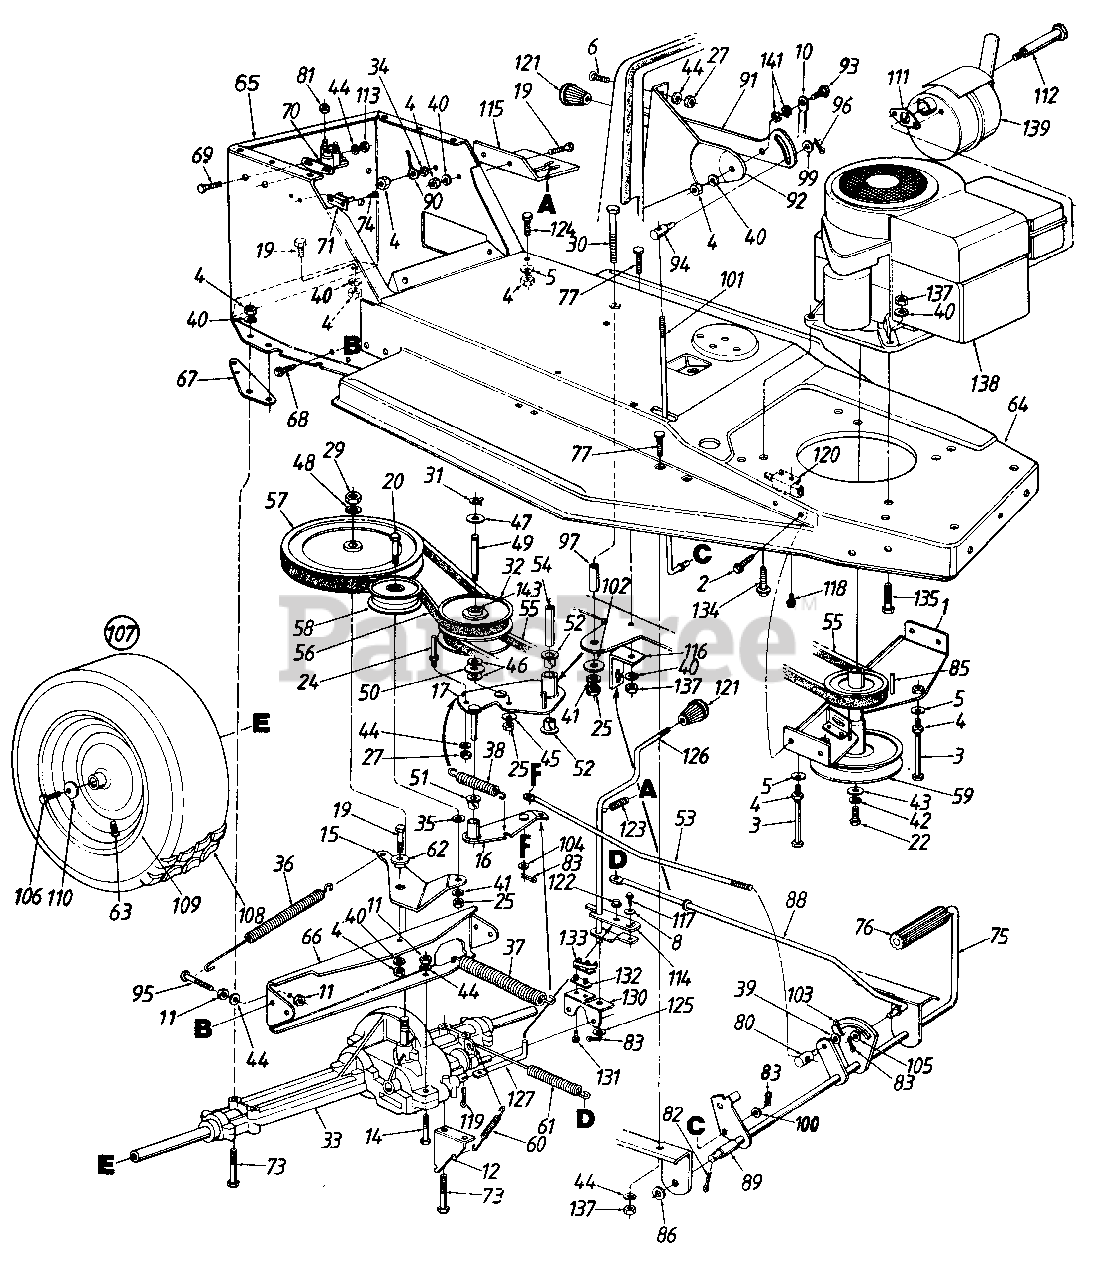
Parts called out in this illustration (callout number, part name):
1	Engine Pulley Belt Guard Ass'y.
2	Hex AB-Tap Scr. 1/4 x .62"
3	Hex Bolt 5/16-18 x 5-1/4" Lg.
4	Hex Nut 5/16-18 Thd.
5	Bell-Wash. .345" I.D. x .88
6	Truss-Mach. Scr. 1/4-20 x .50"
8	Bell-Wash. .265" I.D. x .75
10	Speed Selector Brace
11	Hex Nut 1/4-28 Thd.
12	Spring Retainer Brkt.
14	Hex Bolt 1/4-28 x 1.75" Lg.
17	Variable Speed Brkt. Ass'y.
19	Hex Bolt 5/16-18 x .75" Lg.
20	Hex Bolt 3/8-24 x 2.0" Lg. Grade 5
22	Hex Bolt 7/16-20 x 1.5" Lg.
24	Belt Guard Pin
25	Hex Nut 3/8-24 Thd.
27	Hex Nut 1/4-20 Thd.
29	Hex Jam Nut 1/2-20 Thd.
30	Hex Bolt 3/8-24 x 3.75" Lg.
31	Snap Ring
32	Variable Speed Pulley Ass'y.
33	Transaxle Complete
34	Ext. L-Wash. 5/16" I.D.
35	Fl-Wash. 3/8" I.D. x 1.0" O.D.
36	Extension Spring 6.12" Lg.
37	Extension Spring 7.5" Lg.
38	Extension Spring 2.59" Lg.
39	Fl-Wash. .385" I.D. x .620"
40	L-Wash. 5/16" I.D.*
41	L-Wash. 3/8" I.D.
42	L-Wash. 7/16" I.D.
43	Fl-Wash. .450" I.D. x 1.25"
44	L-Wash. 1/4" I.D.
45	Bell-Wash. .39" I.D. x 1.13"
46	Fl-Wash. .56" I.D. x 1.0" O.D.
47	Washer"Teflon" .565 I.D.
48	Bell-Wash. 1/2" I.D. x 1.0" O.D.
49	Shaft .56" Dia. x 3.875" Lg.
50	Thrust Brg. 1.25 O.D.
51	Flanged Nyliner Brg.
52	Nyliner Flanged Brg.
53	Speed Control Rod
54	Spacer
55	V-Belt
56	V-Belt
57	1/2 V-Pulley .501 " I.D. x 8.00"
58	Idler Pulley 3-1/8" Dia.
59	Dbl. Pulley 6.0" Dia. x 3.56"
60	Extension Spring 3.18" Lg.
61	Extension Spring 7.08" Lg.
62	Shld. Spacer .500" Dia.
63	Air Valve
64	Front Frame
65	Rear Frame
66	Transaxle Support Brkt.
69	Hex Bolt 1/4-20 x .62" Lg.
70	Solenoid
71	Circuit Breaker
73	Hex Bolt 5/16-18 x 2.75" Lg.
74	Truss Mach. B-Tap Scr. #10 x.50" Lg.
75	Foot Pedal Rod Ass'y.
76	Foot Pad
77	Ribbed Neck Bolt 5/16-24 x .84"
80	Ferrule
81	Hex Sems Nut 1/4-20 Thd.
82	Cot-Pin 1/8" Dia. x 1.25" Lg.
83	Cot-Pin 3/32" Dia. x .75" Lg.
85	Sq. Key 1/4 x 2.0" Lg.
86	Fl-Wash. .635" I.D. x 1.0"
88	Brake Rod
89	Spacer 5/8" I.D. x 1.2" Lg.
90	Ground Wire 7.25" Lg.
91	Speed Selector Lever
92	5 Speed Selector Brkt.
93	Shld. Bolt .437" Dia. x .47" Lg.
94	Ferrule
95	Hex Bolt 1/4-28 x 1.25" Lg.
96	Intern. Cot-Pin 5/16" Dia.
97	Spacer .375" I.D. x .625"
99	Fl-Wash. .344" I.D. x .62"
100	Fl-Wash. .25" I.D. x .62" O.D.
101	Speed Control Rod
102	Fl-Wash. 3/8" I.D. x .1" O.D.
103	Cot-Pin 1/8" Dia. x 1.0" Lg.
104	Fl-Wash. .34" I.D. x .68"
105	Fl-Wash..34" I.D.
106	Hex L-Bolt 5/16-24 x .75" Lg.
110	Bell-Wash. .345" I.D. x .88"
111	Exhaust Gasket
112	Shld. Bolt 7/16" Dia. x 3-5/8" Lg.
113	Hex Jam Nut 1/4-20 Thd.
114	Shift Lever Adjusting Link
115	Shift Lever Spring Brkt.
118	Hex B-Tap Scr. #10 x .38" Lg.
119	Intern. Cotter Pin
120	Safety Switch
121	Knob
122	Retaining Ring
123	Compression Spring 1.5" Lg.
124	Hex Wash. Hd. Scr. 5/16-18 x .62" Lg.
125	Fl-Wash. .469" I.D. x .88"
130	Shift Lever Support
131	Hex Wash. Hd. #8 x .50" Lg.
132	Insulator Nut Plate
133	Spring Switch
134	Hex Tap Scr. 3/8-16 x 1.25"
135	Hex Bolt 5/16-24 x 1-1/4" Lg. Grade 5
137	Hex Nut 5/16-24 Thd.
138	Engine
139	Muffler
141	Wave Wash. .445" I.D.
143	Needle Brg.
